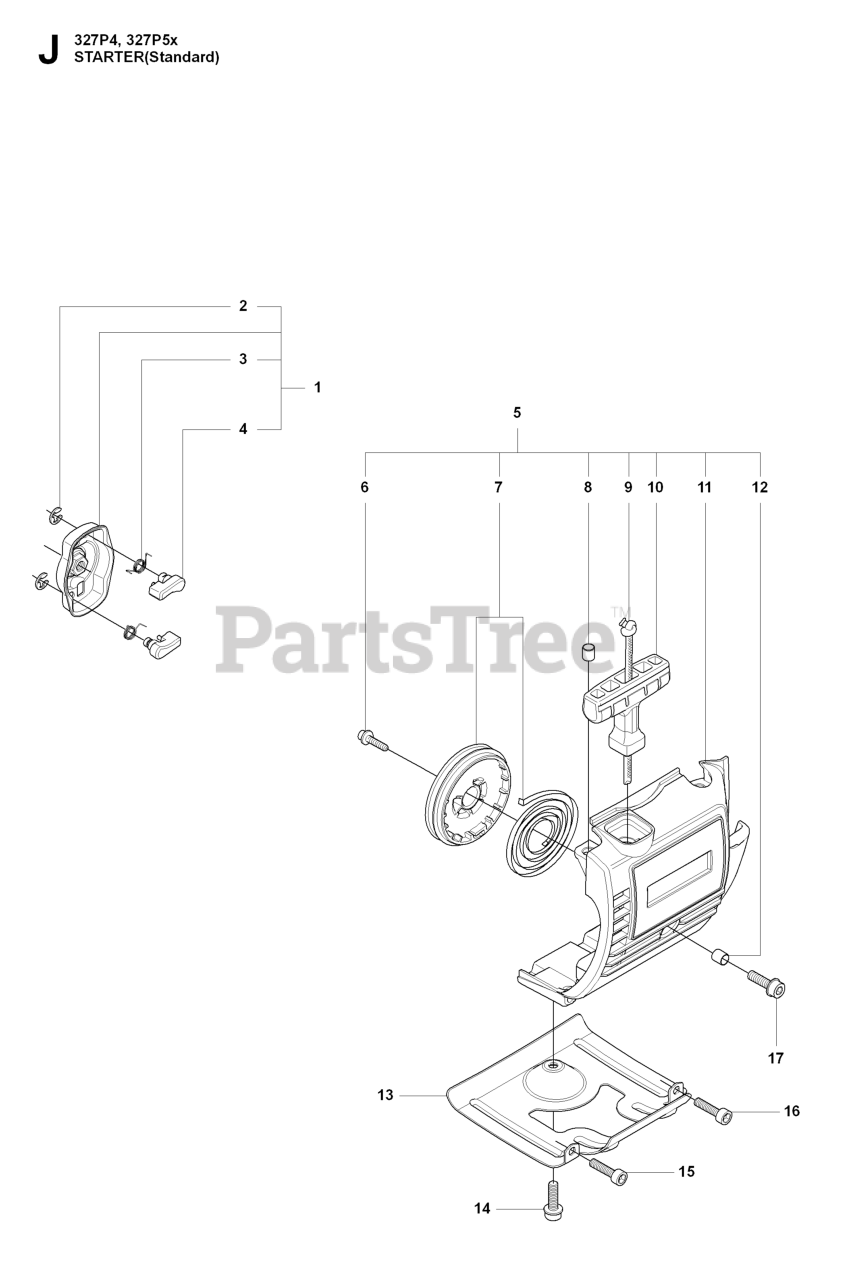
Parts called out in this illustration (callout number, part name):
1	STARTER PAWL BRIDGE
4	STARTER PAWL
5	STARTER ASSY
7	STARTER PULLEY ASSY.
8	SPACING SLEEVE
9	STARTER ROPE
10	STARTER HANDLE
11	RP STARTER HOUSING
12	SPACING SLEEVE
14	SCREW
17	SCREW
